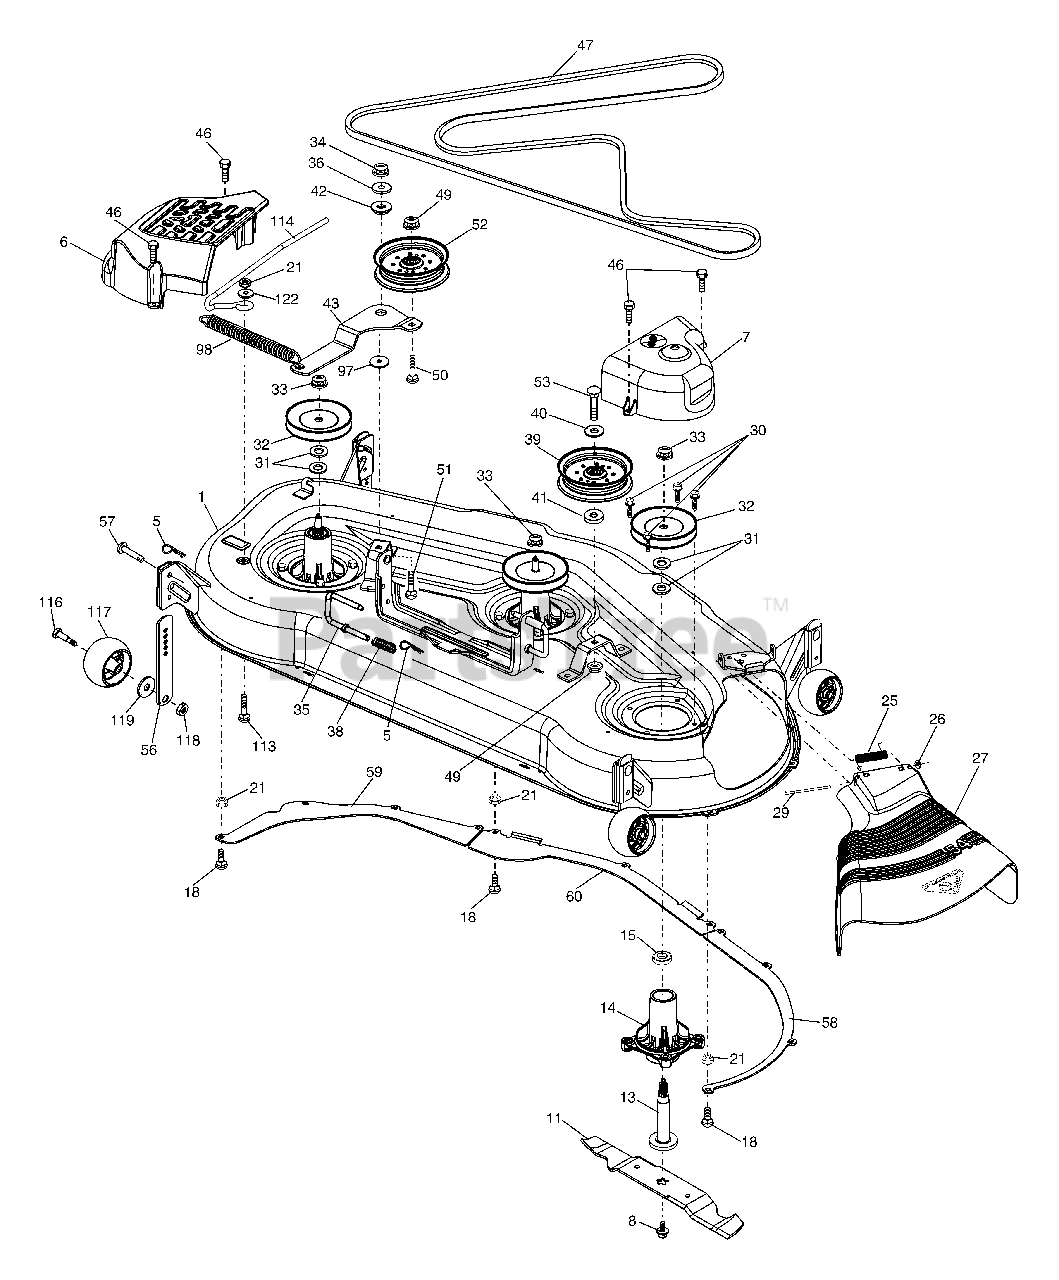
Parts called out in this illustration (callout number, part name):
1	Deck Weldment Mower
5	Retainer Spring
6	Cover Mandrel LH
7	Cover Mandrel RH
8	Bolt 7/16 Asm. Blade
11	Blade Standard
13	Shaft Asm. w/Lower Bearing
14	Mandrel Housing
15	Bearing, Ball, Mandrel
18	Bolt Carr 5/16-18 x 5/8
21	Nut, Crownlock 5/16-18 unc
25	Spring Torsion
27	Deflector Shield
29	Rod, Hinge
30	Screw Thd Roll
31	Washer, Spacer Mower Vented
32	Pulley, Mandrel
33	Nut, Flg. Top Lock Cntr. 9/16
35	Pin Suspension Rear
36	Washer 13/32 x 13/16 x 16 Ga.
38	Spring Compression
39	Pulley, Idler, Stationary
40	Washer 13/32 x 1-3/8 x 3 Ga.
41	Washer 13/32 x 13/16 x 12 Ga.
42	Spacer, Retainer
43	Arm, Idler
46	Screw, Thdroll. 1/4-20 x 5/8
47	V-Belt, Mower, Secondary
49	Nut, Lock Flg. 3/8-16 unc
50	Bolt, Carr. 3/8-16 x 2
51	Bolt 3/8-16 x 1-1/4 Gr. 5
52	Pulley Idler clutching
53	Bolt Fin Hex 3/8-16 unc x 2-1/4
56	Bar Pnt Adj.
57	Pin Head Rivet
58	Baffl e Right
59	Baffl e Left
60	Baffl e Center
97	Washer Hardened
98	Spring Clutch Drive
113	Bolt Rdhd Sqnk 5/16-18 unc x 3/4
114	Rod Tension Relief
116	Bolt, Shoulder
117	Gauge Wheel
118	Nut, Centerlock 3/8-16 unc
119	Washer 3/8 x 7/8 x 14 Ga.
122	Bushing Tension Relief
